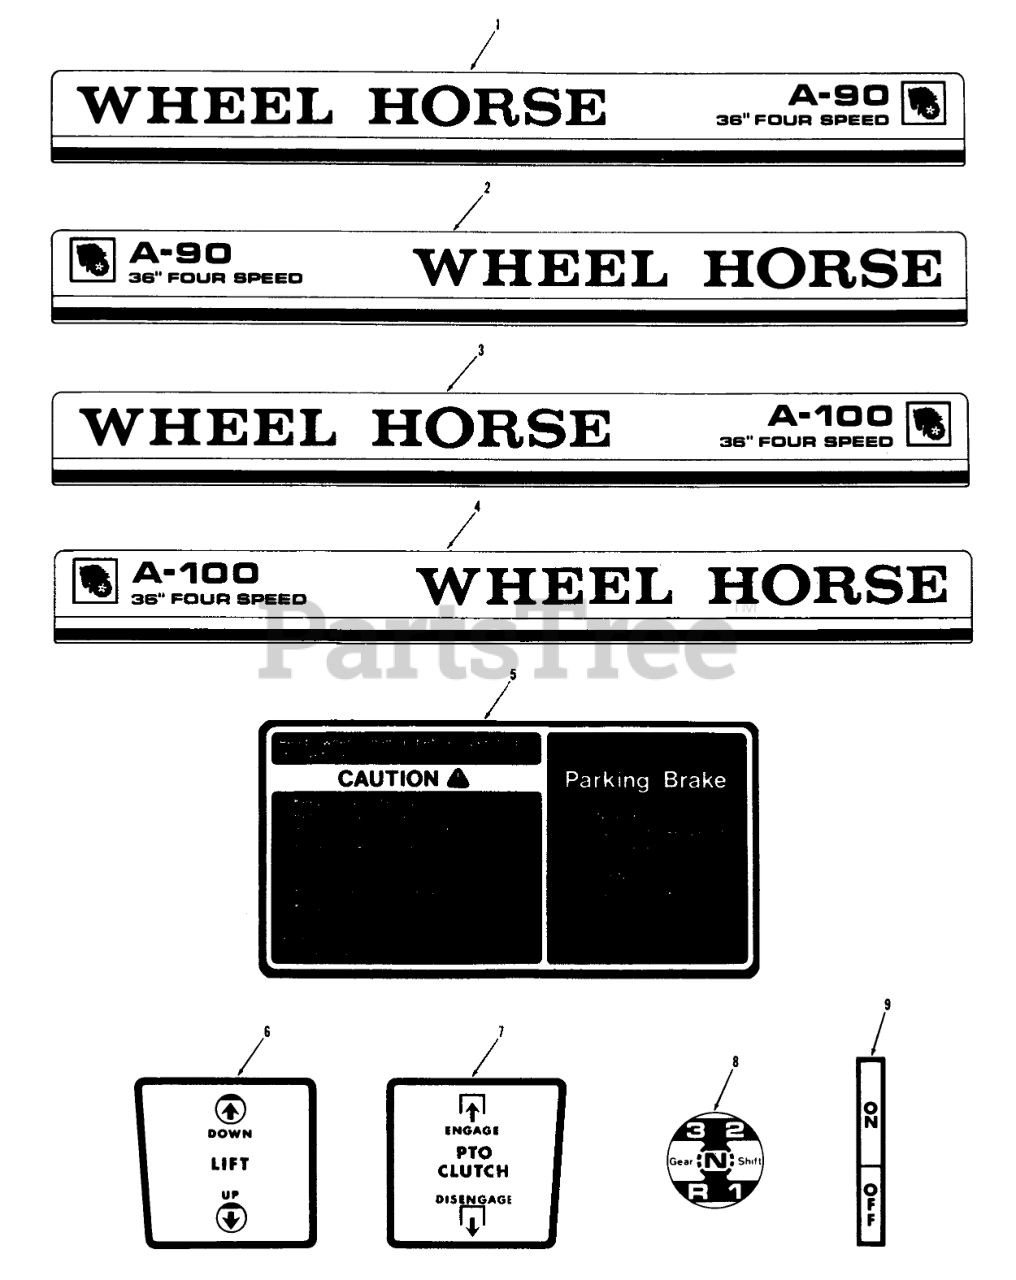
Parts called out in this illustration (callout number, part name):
1	Decal-Hood A-90 RH
2	Decal-Hood A-90 LH
3	Decal-Hood A-100 RH
4	Decal-Hood A-100 LH
5	Decal-Caution
6	DECAL-HAND LIFT
7	Decal
8	DECAL-4 SPD SHIFT
9	Decal-Off/On
